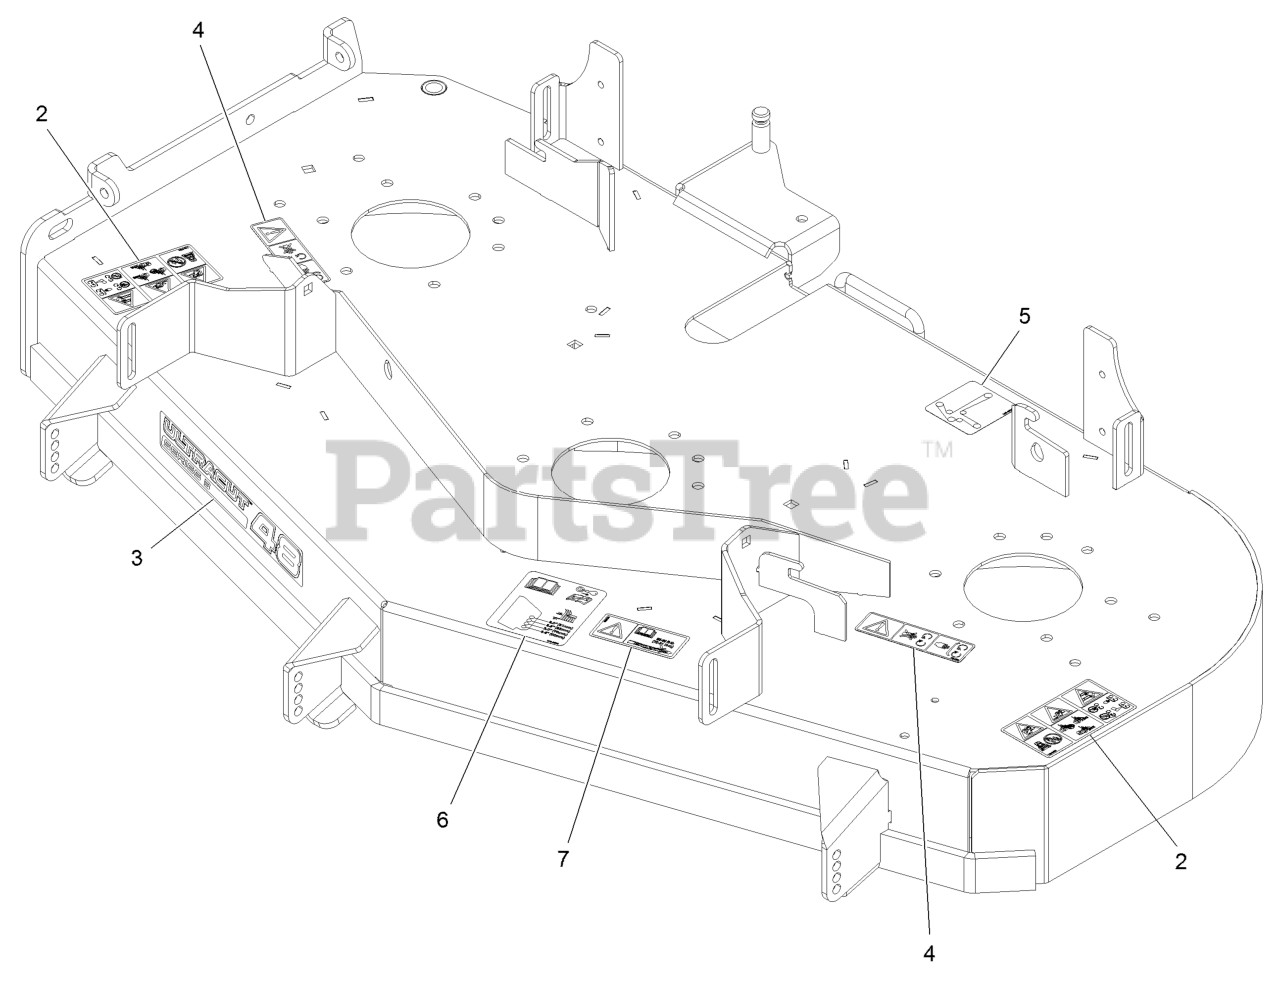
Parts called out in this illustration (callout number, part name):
2	DECAL-DANGER THROWN OBJECTS
3	DECAL-ULTRACUT 48 SERIES
4	DECAL-COVER, MISSING
5	DECAL-ROUTING, BELT
6	DECAL-ROLLER, ANTI-SCALP
7	DECAL-BOLT TORQUE
